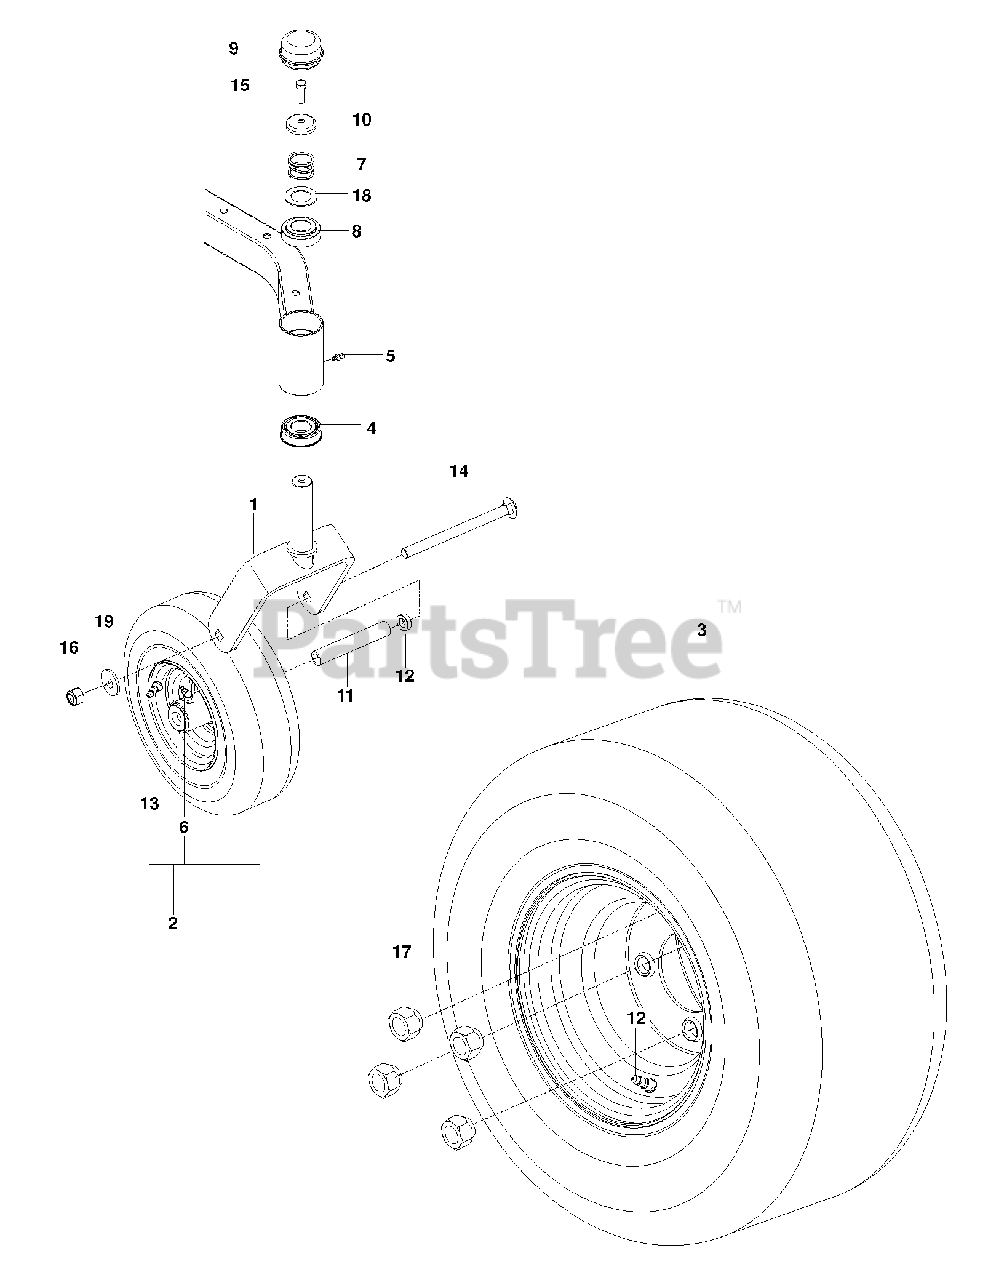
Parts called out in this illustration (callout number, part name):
1	YOKE.CASTER.ORANGE
2	WHEEL.11X4-5.K404LG.5X3W/4.188
3	WHEEL.ASSEM.18X8.5-8.KENDA.ZTR
4	BEARING FLANGED
5	ZERK, 3/16, DRIVE IN
6	ZERK
7	SPRING, CASTER
8	BUSHING, CASTER
9	GREASE CAP
10	CASTER.PLUG
11	SPACER SPLIT
12	SPACER, 5/16"
13	VALVE STEM TR-412
14	RHSNB 1/2-13 X 6.50 GR2 ZD
15	5/16-18X1 HHB G5W/NY
16	NUT 1/2-13 HEX CNTRLK GR 5 ZD
17	LUG NUT 1/2F
18	WASHER, 1.025 ID X 1.64
19	WASHER.9/16 X 1 3/8 X 12 GA.
